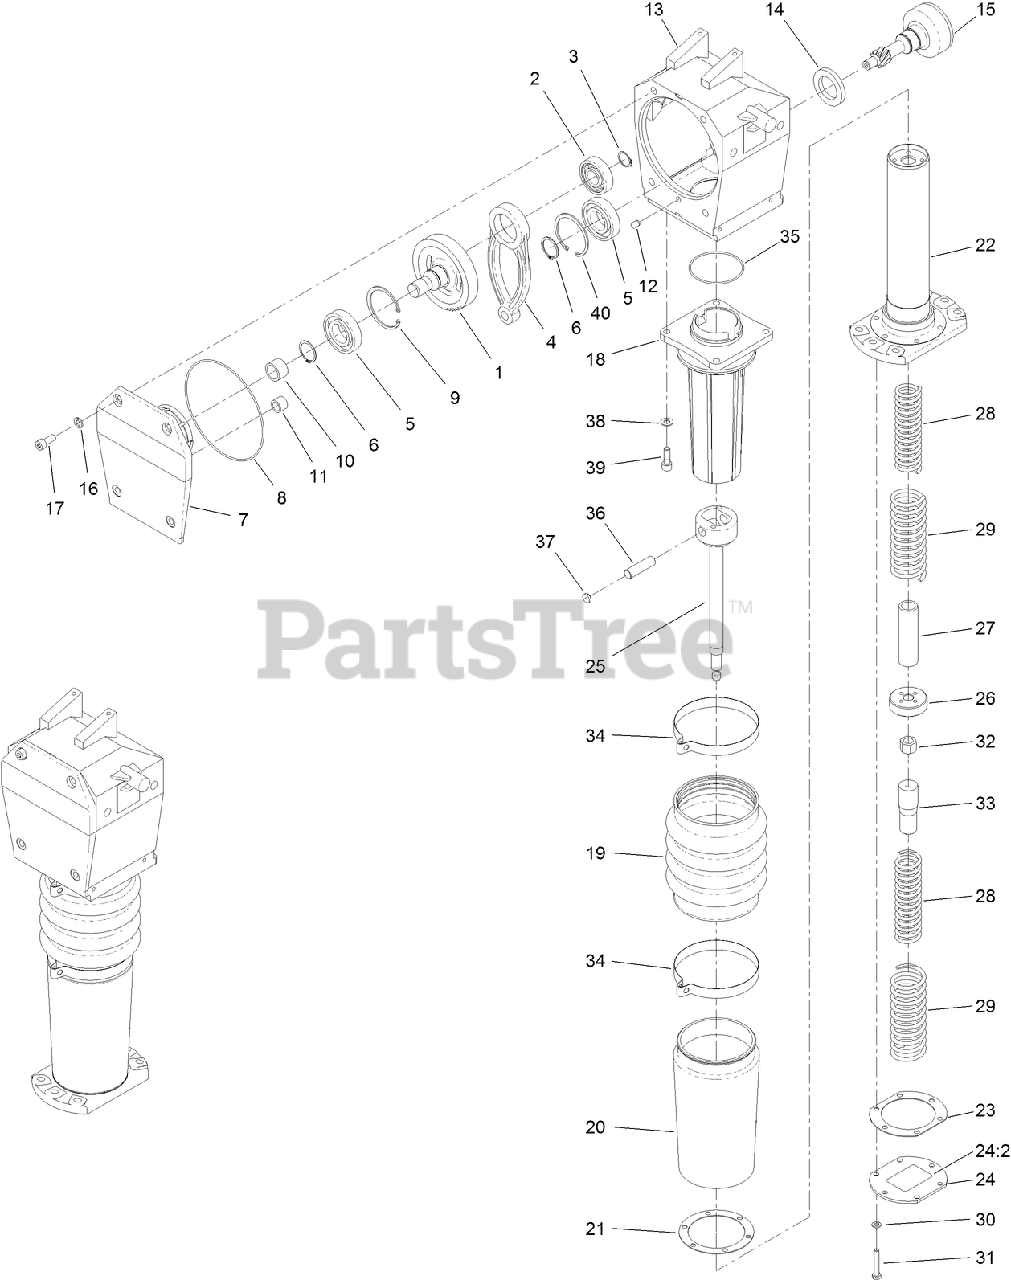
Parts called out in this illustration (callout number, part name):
1	GEAR-HELICAL
2	BEARING-BALL
3	RING-EXTERNAL
4	ROD-CONNECTING
5	BEARING-BALL
6	RING-SNAP, EXTERNAL
7	COVER-FRONT
8	O-RING
9	RING-INTERNAL
10	BEARING-NEEDLE
11	BEARING-NEEDLE
13	GEARCASE
14	SEAL-SHAFT
15	PINION
17	SCREW-HSH
18	GUIDE-TUBE
19	BOOT-AWACK
20	COVER-HOUSING, SPRING
21	GASKET-HOUSING, SPRING COVER
23	GASKET-COVER, SPRING
24	BOTTOM SPRING COVER ASM
24:2	DECAL-WARNING, SPRING
25	ROD-PISTON
26	PUCK-PISTON
27	SNUBBER-AXIAL, TOP
28	SPRING-COMPRESSION, INNER
29	SPRING-COMPRESSION, OUTER
30	WASHER-LOCK
31	SCREW-HH
32	NUT-LOCK, NI
33	SNUBBER-AXIAL, LOWER
34	CLAMP-BOOT, STOMPER
35	O-RING
37	BUTTON-PIN, CAPTIVATOR
38	WASHER-FLAT
39	SCREW-HSH
40	RING-INTERNAL
